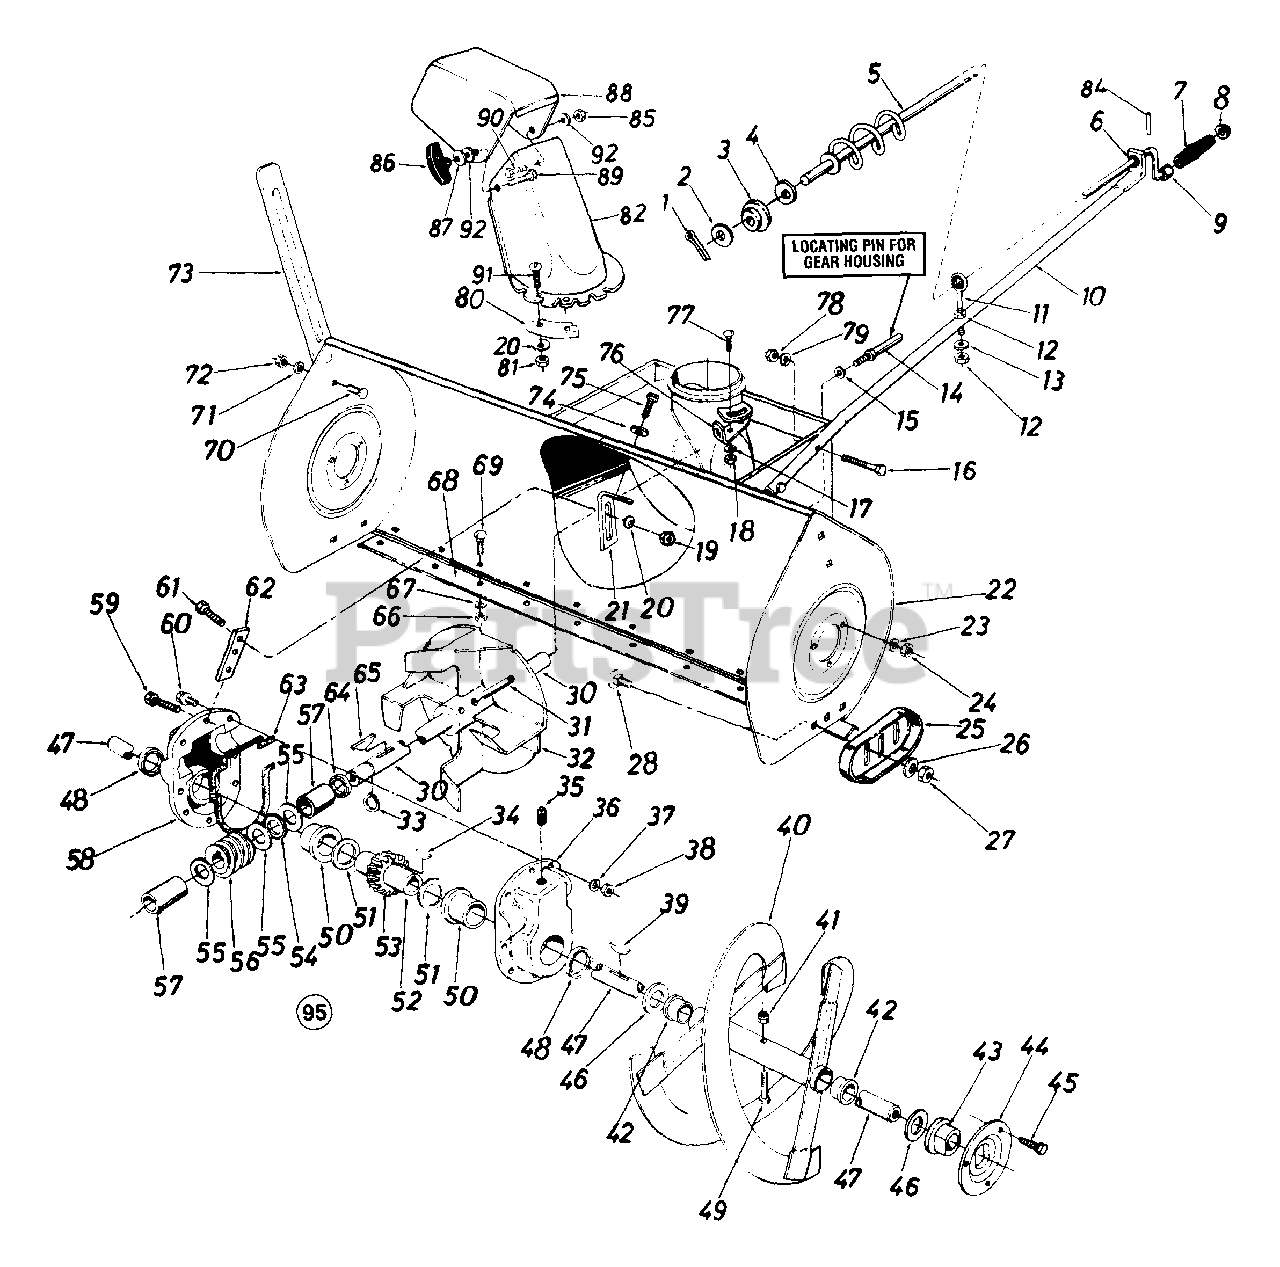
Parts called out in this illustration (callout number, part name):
2	Fl-Wash. .39" I.D. x .62" O.D.
3	Plastic Bushing
4	Fl-Wash. .385" I.D. x .62" O.D.
5	Chute Crank Ass'y.
6	Plastic Bushing
7	Knob
8	Push Nut 3/8" Rod
9	Spacer .385 I.D. x .50" O.D.
12	Hex Nut 5/16-18 Thd.
13	Bell-Wash. .345" I.D. x .88" O.D.
14	Stud 3/8-16 x 2.75" Lg.
15	Bell-Wash. .40" I.D. x .88" O.D.
16	Hex Bolt 3/8-24 x 1.25" Lg.
17	Bell-Wash. .345" I.D. x .88" O.D.
18	Hex Nut 5/16-18 Thd.
19	Hex Nut 1/4-28 Thd.
20	Bell-Wash. .265" I.D. x .75" O.D.
22	45" Snow Thrower Housing Ass'y.
23	L-Wash. 5/16" I.D.
24	Hex Nut 5/16-18 Thd.
26	Bell-Wash. .40" I.D. x .88" O.D.
27	Hex Jam Nut 3/8-16 Thd.
28	Carriage Bolt 3/8-16 x .62" Lg.
30	Blower Axle .875" Dia. x 14.75" Lg.
31	Spring Pin Spir. 5/16" Dia. x 1.75" Lg.
34	#91 Woodr-Key 1/4 x 3/4" Dia. (HDN)
36	Comp. Gear Hsg. Half - L.H.
37	Spr-Wash. .32" I.D. x .62" O.D.
38	Hex Ins. L-Nut 5/16-18 Thd.
39	#91 Woodr-Key 1/4 x 3/4" Dia. (HDN)
41	Hex Ins. L-Nut 5/16-18 Thd.
42	Plastic Bushing
43	Flange Brg. w/Flats 1" I.D.
44	Bearing Housing
45	Hex Sems Bolt 5/16-18 x .75" Lg.
46	Fl-Wash. 1.0" I.D. x 1.75" O.D.
48	Flange Bearing 1.503" I.D.
49	Shear Bolt 5/16-18 x 1.75" Lg.
50	Oil Seal 1.50" I.D.
51	Fl-Wash. 1.50" I.D. x 2.0" O.D.
52	Worm Gear Shaft
53	Double Threaded Worm Gear - L.H.
54	Thrust Brg. .88" I.D. x 1.44" O.D.
55	Fl-Wash. .88" I.D. x 1.4" O.D.
56	Double Threaded Worm - L.H.
57	Sleeve
58	Complete Gear Hsg. Half - R.H.
59	Hex Bolt 5/16-18 x 1.25" Lg.
60	Hex Bolt 5/16-18 x 1.0" Lg. (Gr. 5)
61	Hex Bolt 1/4-28 x .75" Lg.
62	Gear Housing Support Plate
63	Rubber Gasket
64	Oil Seal - .875" I.D.
65	#9 Hi-Pro Key 3/16 x 3/4" Dia. (HT)
66	Hex Nut 5/16-18 Thd.
67	L-Wash. 5/16" I.D.
69	Carriage Bolt 5/16-18 x 1.0" Lg.
70	Carriage Bolt 5/16-18 x .62" Lg.
71	L-Wash. 5/16" I.D.
72	Hex Nut 5/16-18 Thd.
73	Guide Blade
74	Bell-Wash. .345" I.D. x .88" O.D.
75	Hex Wash. Hd, AB-Tap Scr. 5/16 x .75" Lg.
77	Carriage Bolt 5/16-18 x .75" Lg.
78	Hex ins. L-Nut 3/8-24 Thd.
79	L-Wash. 3/8" I.D.
80	Chute Flange Keeper
81	Hex Nut 1/4-20 Thd.
82	Lower Chute Ass'y.
84	Bell-Wash. .345" I.D. x .88" O.D.
85	Hex Cent. L-Nut 5/16-18 Thd.
86	Knob Handle
87	Bell-Wash. .345" I.D. x .88" O.D.
88	Upper Chute Ass'y.
89	Carriage Bolt 5/16-18 x 1.0" Lg.
90	Carriage Bolt 5/26-18 x .62" Lg.
91	Truss Mach. Scr. 1/4-20 x .75"
92	Roll Pin .12" Dia. x .63"
95	Worm Gear Box Ass'y. Comp.
